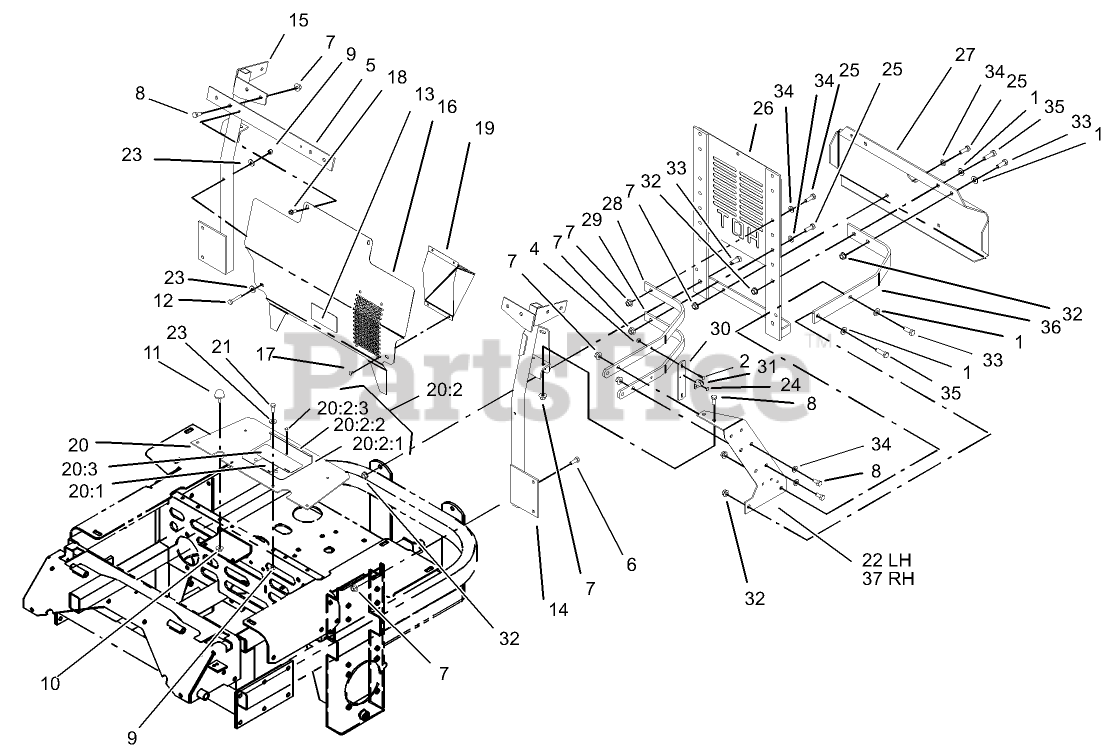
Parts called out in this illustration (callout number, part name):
1	WASHER-FLAT
2	SCREW-HEAD, TRUSS
4	NUT-LOCK, NI
5	CROSSBAR
6	SCREW-HH
7	NUT-HF
8	SCREW-HH
9	NUT-LOCK, NI
10	NUT-HF
11	BUMPER
12	SCREW-HH
13	DECAL-ROUTING, BELT
14	Brace-Radiator, LH
15	BRACE-RADIATOR, RH
16	Deflector-Air
17	RIVET-POP
18	SCREW-HWHTF
19	Plenum-Intake, Air
20	SHIELD ASM
20:1	DECAL-IMPORTANT
20:2	SHIELD AND LIFT ASM
20:2:1	SHIELD-ENGINE
20:2:2	LIFT-SHIELD
20:2:3	RIVET-POP
20:3	DECAL-DEVICES, ROTATING
21	SCREW-HH
22	PLATE-SIDE, LH
23	WASHER-FLAT
24	RIVET
25	SCREW-HH
26	MOUNT-RADIATOR, REAR
27	GUARD-BUMPER
29	RIB-BOTTOM
30	BAR-HOOK, LATCH
31	KEEPER-LATCH, RUBBER
32	NUT-HHF, WHIZ
33	SCREW-HH
34	WASHER-PLAIN
35	SCREW-HH
36	BAR-RADIATOR MOUNT FRAME
37	PLATE-SIDE, RH
